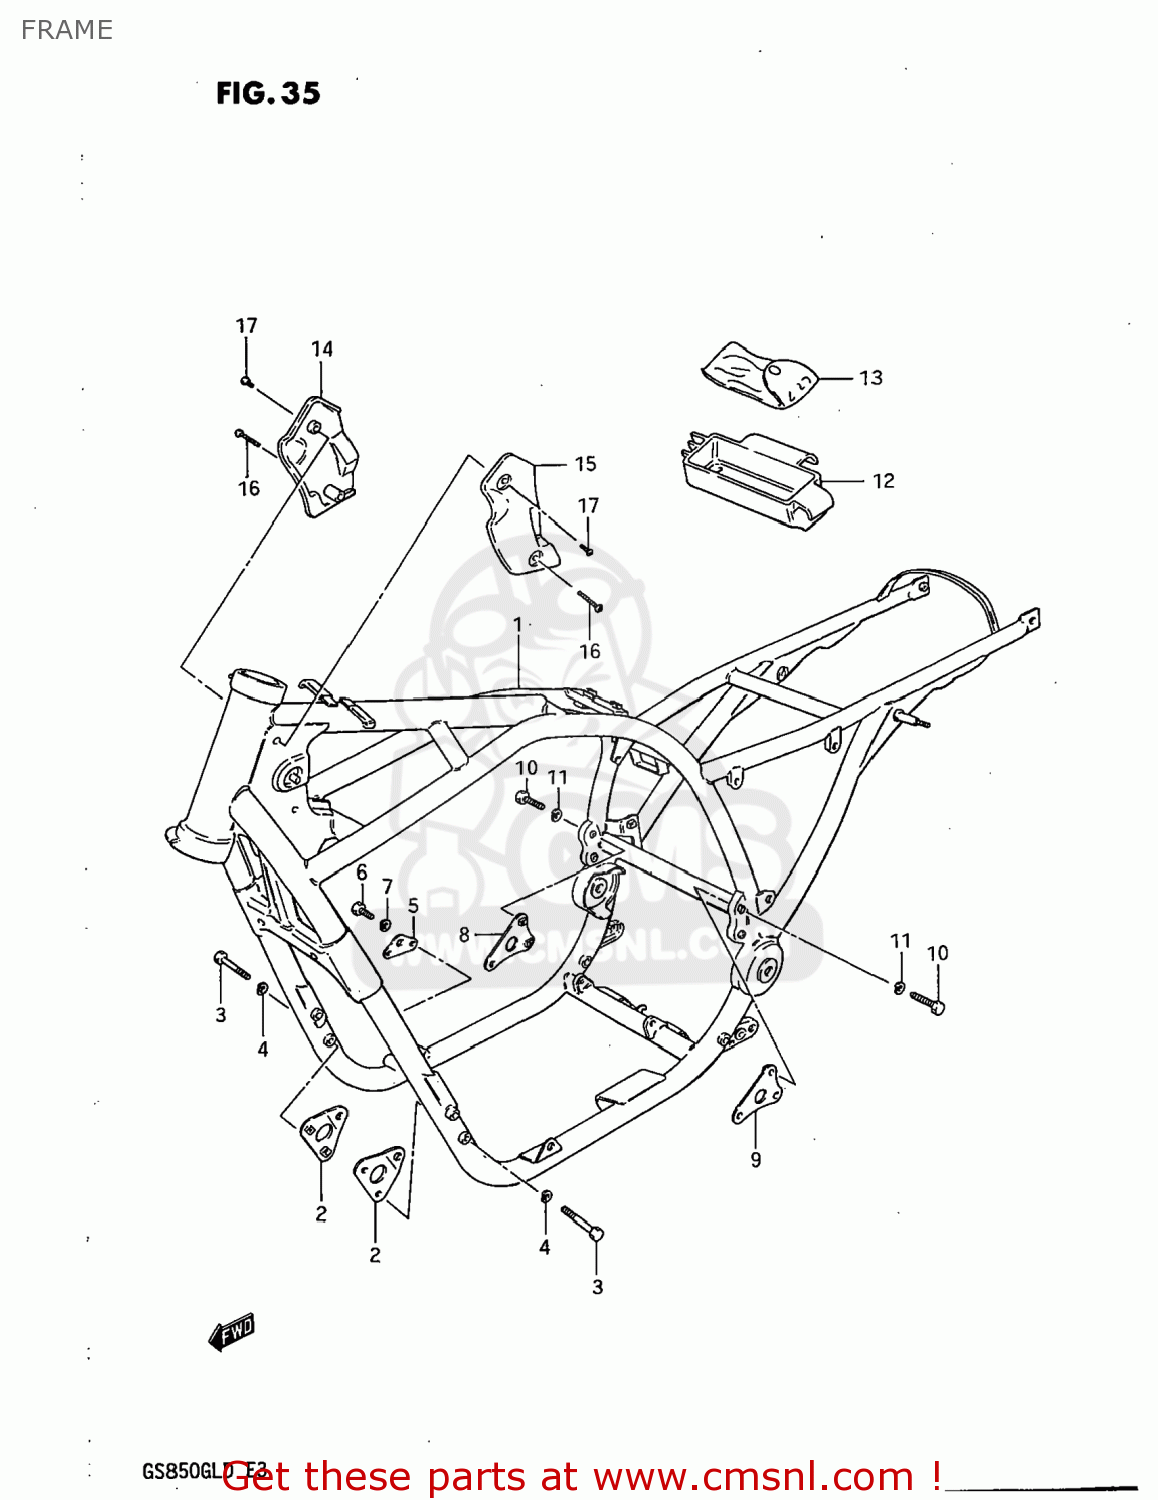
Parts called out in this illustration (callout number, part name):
1	FRAME
2	PLATE,ENGINE MOUNTING
3	BOLT
4	LOCK WASHER
5	PLATE,ENGINE MOUNTING
6	BOLT
7	LOCK WASHER
8	PLATE,ENGINE MOUNTING
9	PLATE,ENGINE MOUNTING
10	BOLT 8X40
11	LOCK WASHER
12	HOLDER,TOOL
13	TOOL SET
14	COVER,FRAME HEAD,RIGHT
15	COVER,FRAME HEAD,LEFT
16	SCREW, LOWER
17	SCREW
